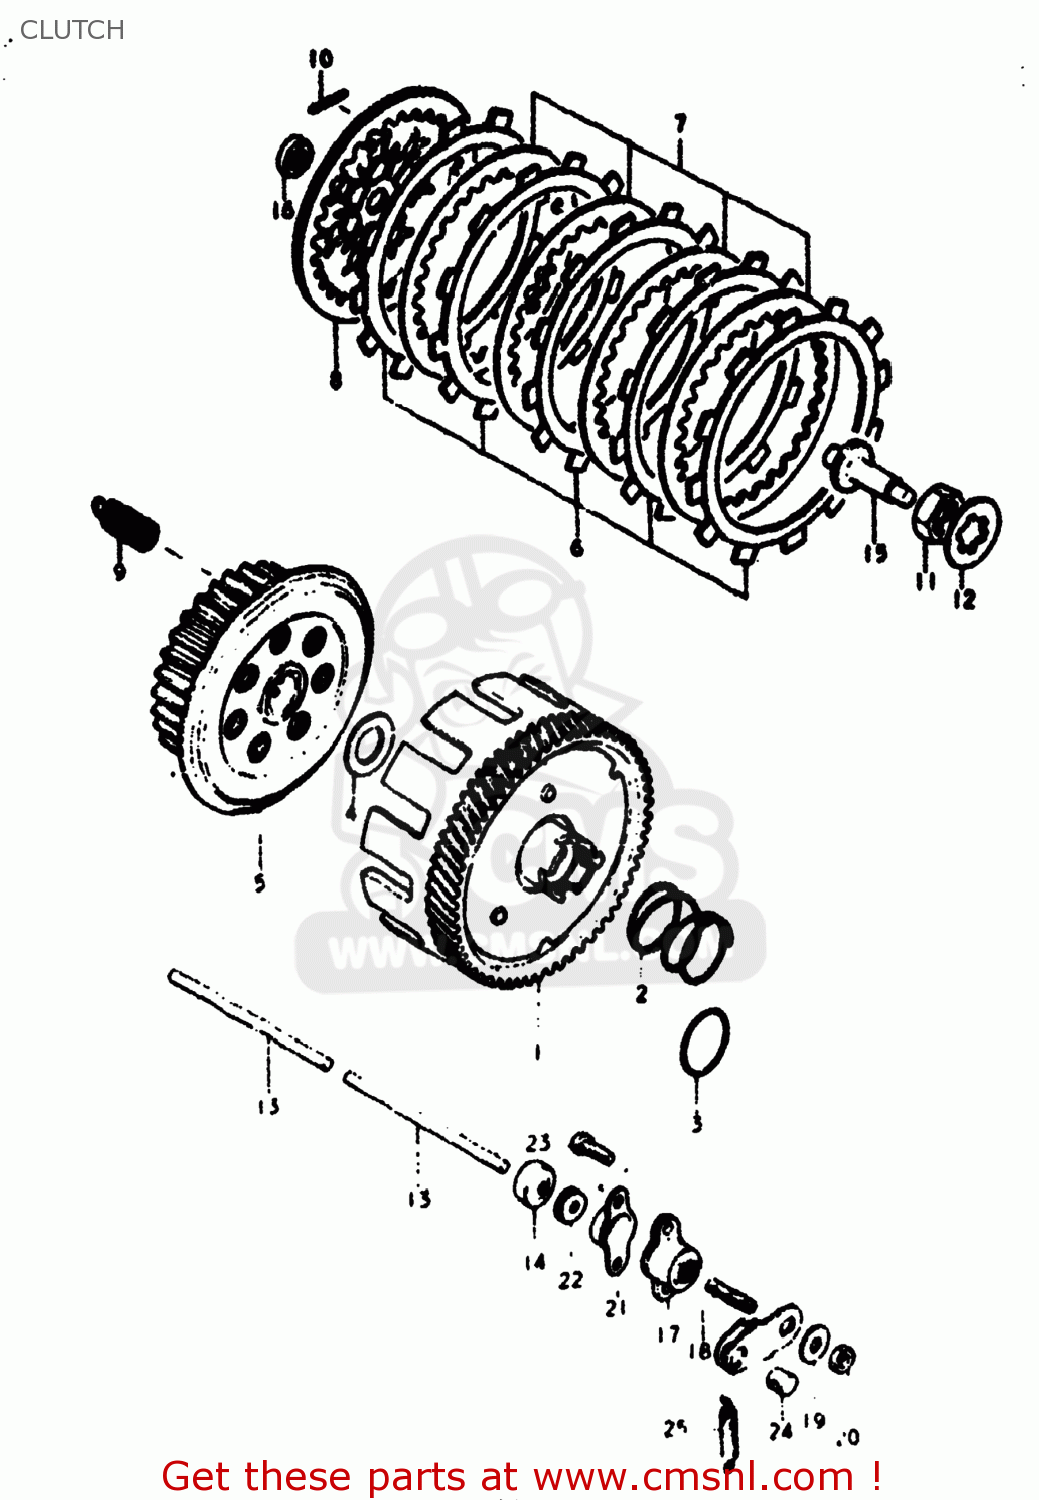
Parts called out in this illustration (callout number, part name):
1	GEAR ASSEMBLY,PRIMARY DRIVE
2	SPRING
3	SPRING
4	WASHER
5	HUB,CLUTCH SLEEVE
6	PLATE,CLUTCH DRIVE
7	PLATE,CLUTCH DRIVEN (NAS)
8	PLATE,CLUTCH PRESSURE
9	SPRING
10	PIN(2.5X19.8)
11	NUT
12	WASHER,LOCK
13	ROD,CLUTCH PUSH
14	OIL SEAL
15	ROD,CLUTCH RELEASE
16	SEAL,OIL (10X17X5)
17	SCREW ASSY,CLUTCH RELEASE
18	SCREW
19	WASHER(6.5X16X1.2)
20	NUT
21	COVER,CLUTCH RELEASE SCREW
22	SEAL,DUST(5.3X13X5)
23	SCREW
24	PIECE,RELEASE ARM END
25	SPRING
